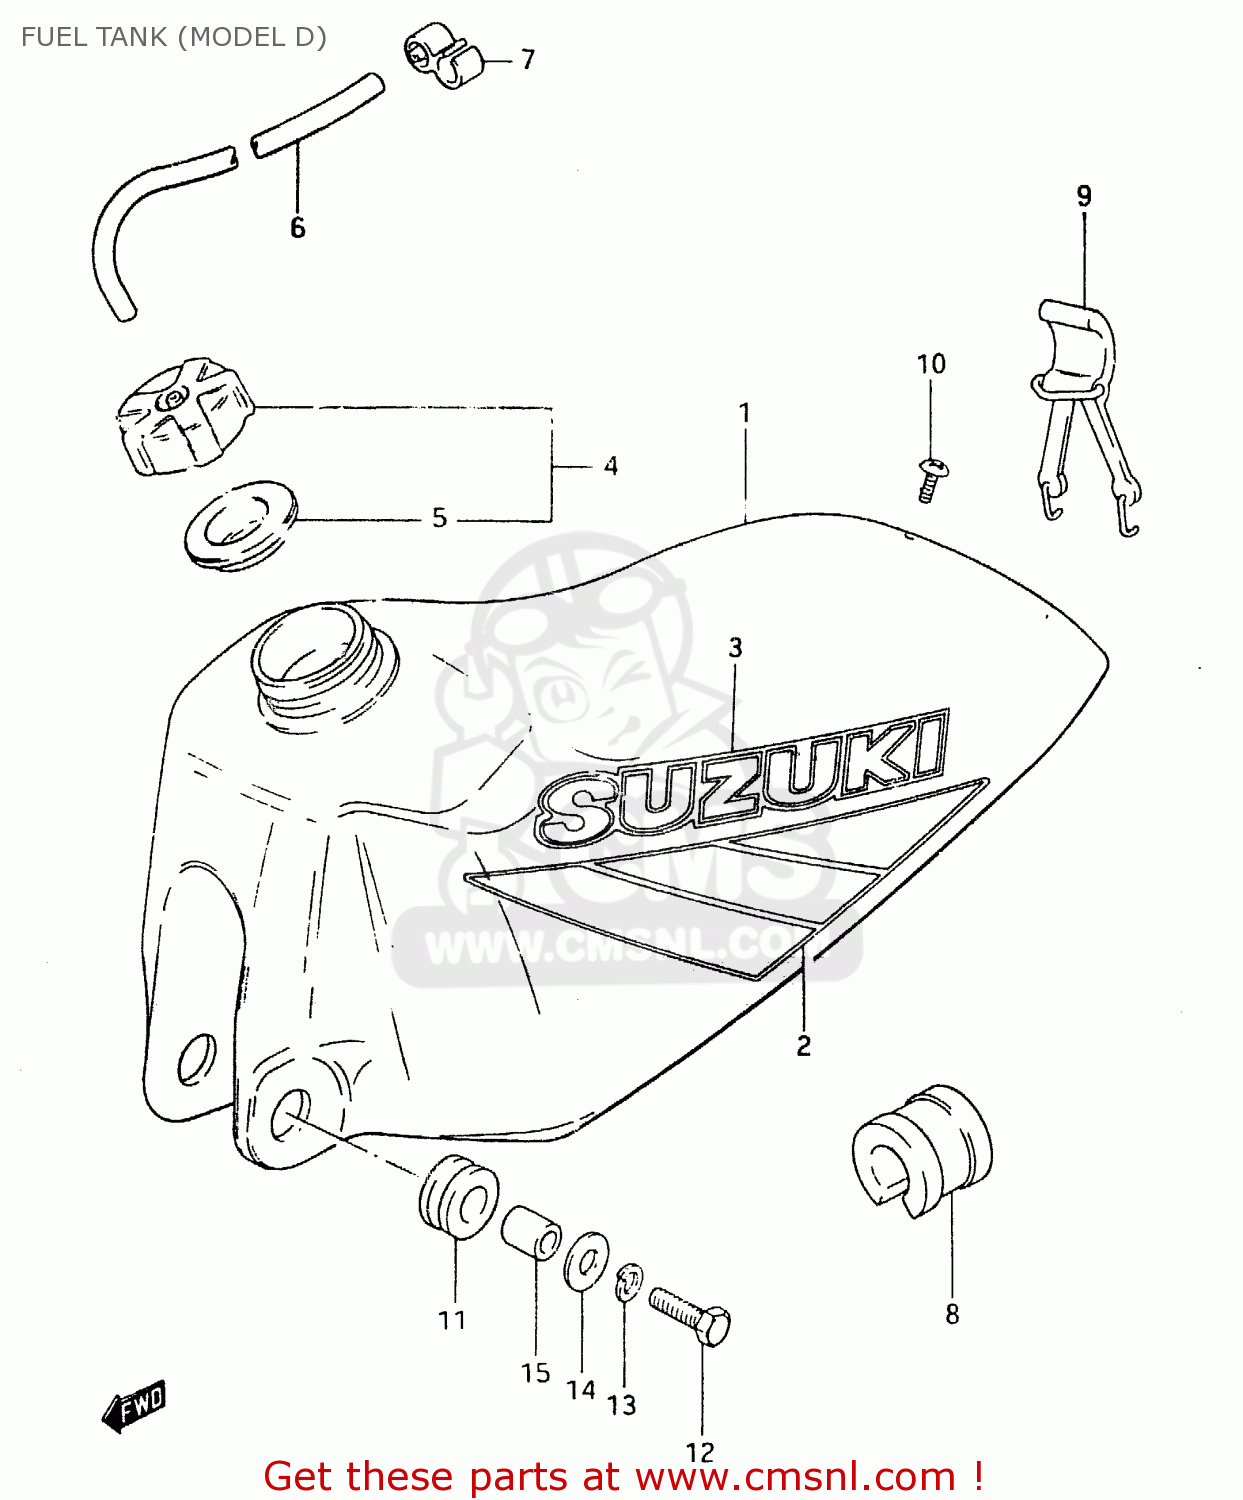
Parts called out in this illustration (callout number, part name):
1	TANK ASSEMBLY,FUEL
2	TAPE SET,FUEL TANK
3	EMBLEM
4	CAP SET,FUEL TANK
5	GASKET,FUEL TANK CAP (NAS)
6	HOSE
7	CLAMP,BREATHER HOSE
8	CUSHION,FUEL TANK UPR
9	BAND,FUEL TANK,REAR
10	SCREW (6X15)
11	CUSHION
12	BOLT (8X30)
13	LOCK WASHER
14	WASHER
15	SPACER (8.8X12X13.5)
